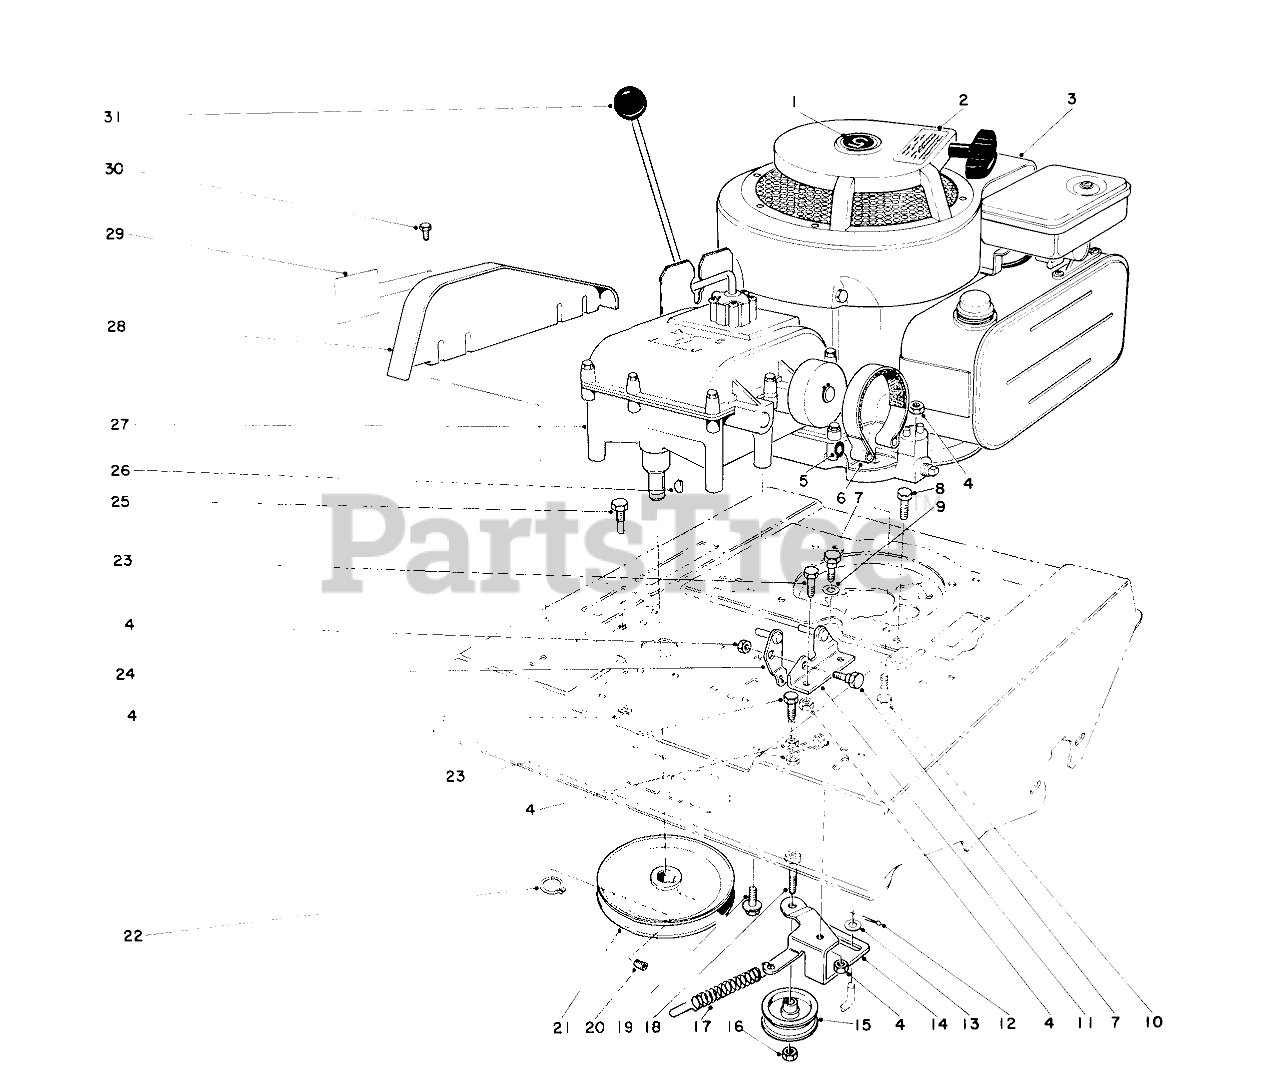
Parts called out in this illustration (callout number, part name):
1	Decal
2	Caution Decal
3	Engine
4	Nut
5	RING-GRIP
6	Brake Band
7	Screw
8	SCREW-HH
9	Washer
10	SCREW-HH
11	Bracket
12	PIN-COTTER
13	WASHER-PLAIN
14	Idler Lever
15	Idler Pulley
16	NUT-LOCK, SIDE
17	Clutch Spring
18	Capscrew
19	SCREW-HHF
20	SCREW-SET, HSH
21	Pulley
22	RING-SNAP, EXTERNAL
23	SCREW-HH
24	Pivot
25	Screw
26	KEY-WOODRUFF
27	Transmission
28	Chain Guard
29	Decal Shift Pattern
30	Self Tapping Screw
